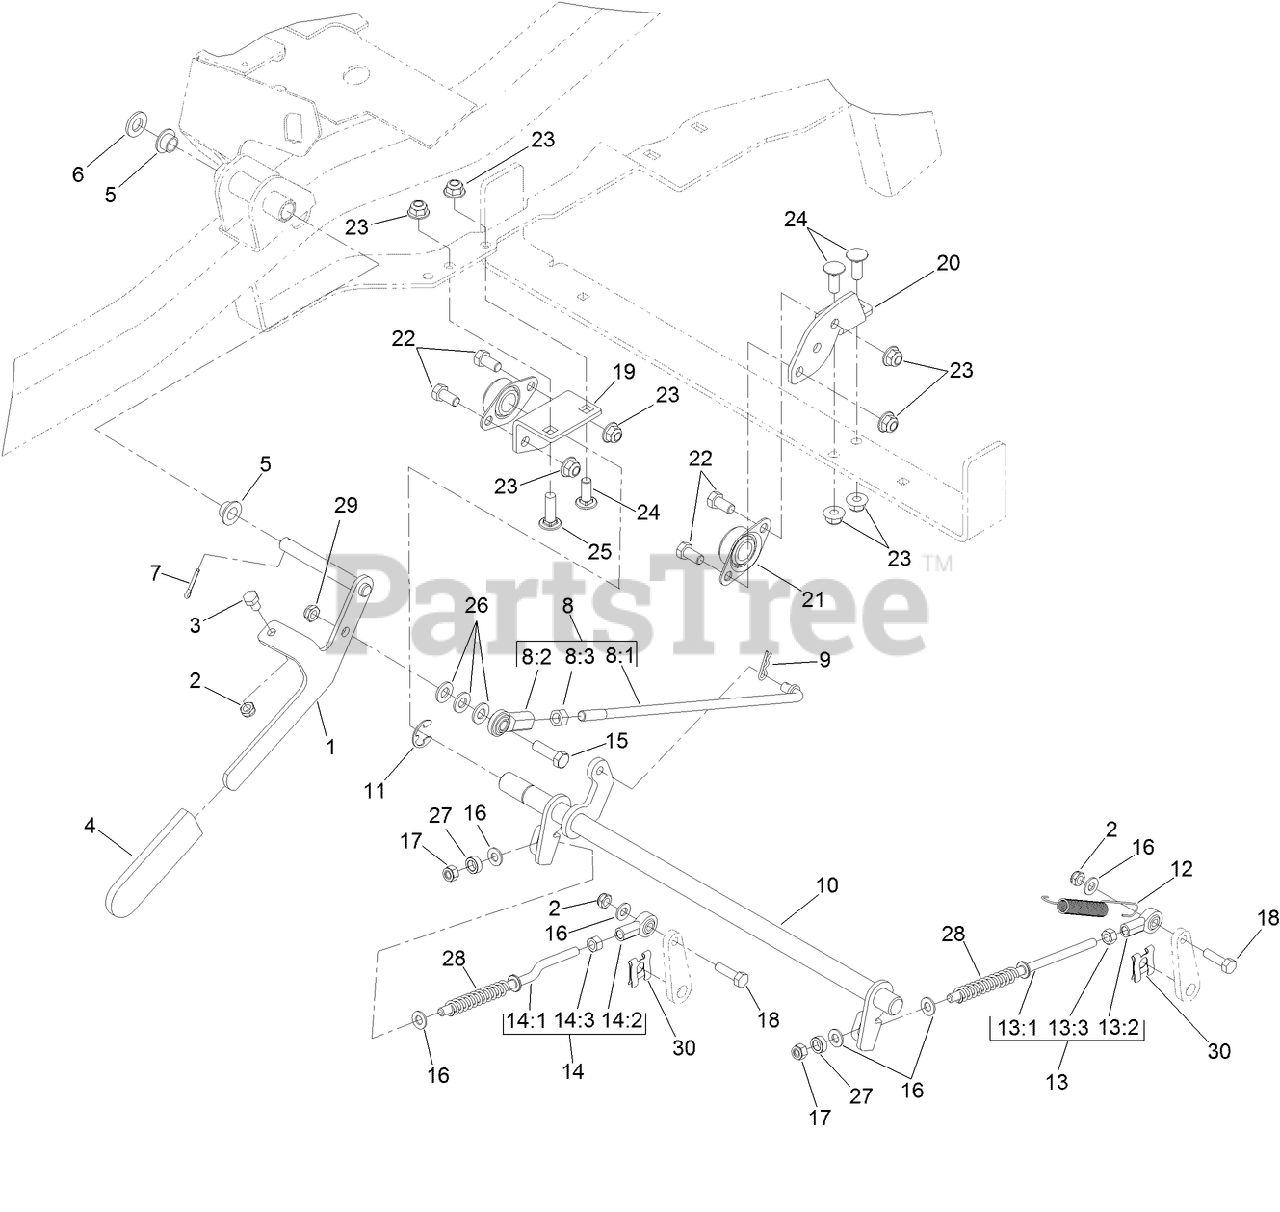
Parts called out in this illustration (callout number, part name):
1	HANDLE-BRAKE
2	NUT-LOCK, NI
3	SCREW-HH
4	GRIP-LEVER
5	BEARING-CONTROL
6	WASHER-FLAT
7	PIN-COTTER
8	BRAKE LINK ASM
8:1	ROD-LINK, BRAKE
8:2	JOINT-BALL, END
8:3	NUT-HEX
9	PIN-COTTER
10	SHAFT-BRAKE
11	E-RING
12	SPRING-EXTENSION
13	LH BRAKE ROD ASM
13:1	ROD-BRAKE
13:2	BALLJOINT-RH
13:3	NUT-HEX
14	RH BRAKE ROD ASM
14:1	ROD-BRAKE
14:2	BALLJOINT-RH
14:3	NUT-HEX
15	SCREW-HH
16	WASHER-PLAIN
17	NUT-LOCK
18	SCREW-HH
19	BRACKET-SHAFT MOUNT, RH
20	BRACKET-SHAFT MOUNT, LH
21	BEARING-FLANGE, SIDE
22	SCREW-HH
23	NUT-HF, NI
24	SCREW-CARR
25	SCREW-CARR
26	WASHER-FLAT
27	SPACER
28	SPRING-RETURN, NEUTRAL
29	NUT-LOCK, NI
30	CLIP-RETAINING
